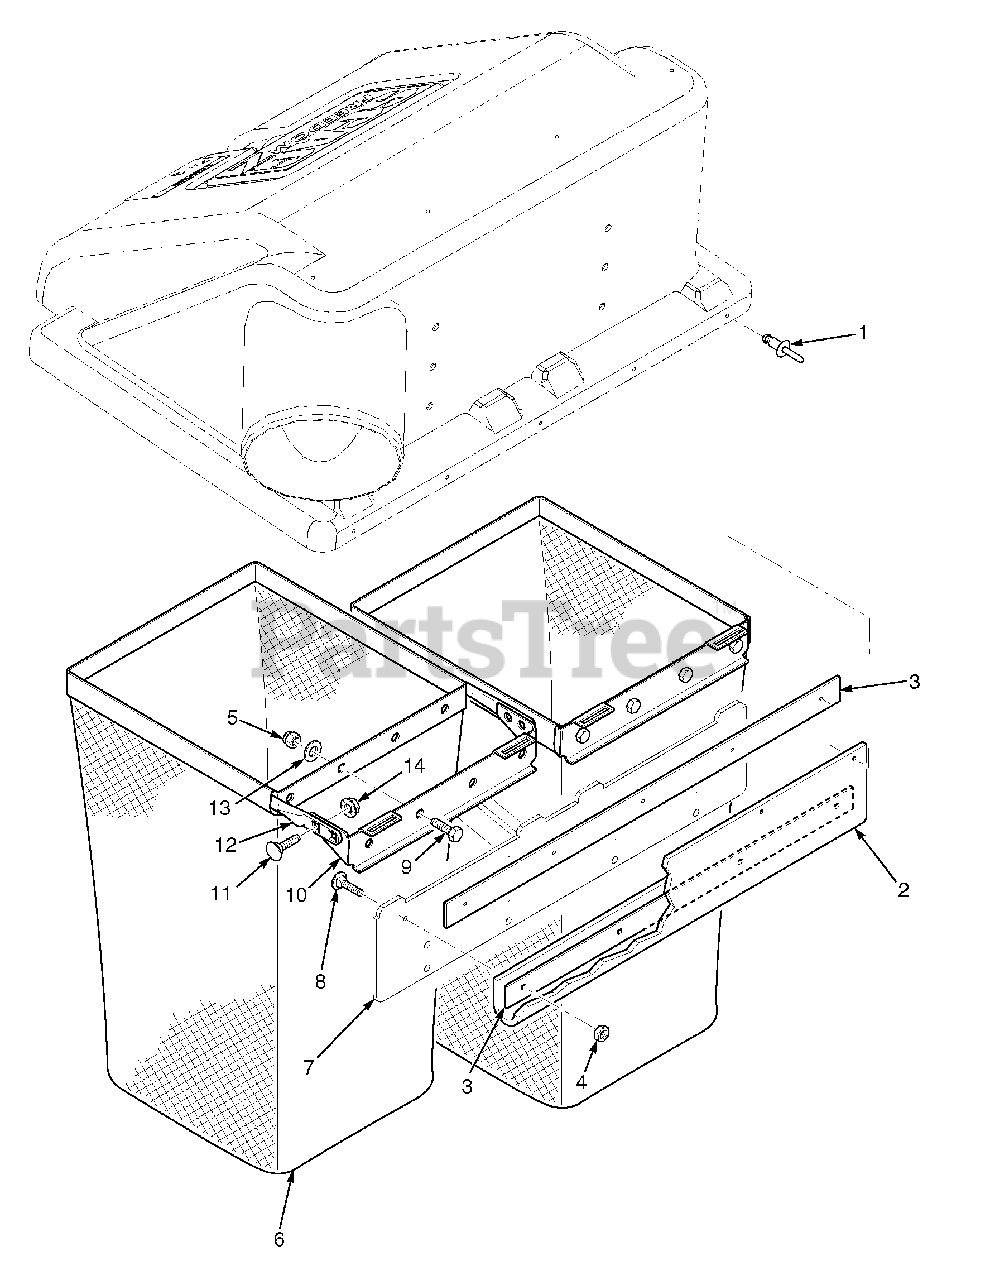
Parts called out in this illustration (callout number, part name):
1	Pop Rivet, 3/16 x .652
2	Seal, GC Hood
3	Retainer, Seal
4	Nut, Center Lock 1/4-20
5	Nut, Elastic Stop 5/16-18
6	Bag Assembly
7	Frame Weldment, Bag Support
8	Bolt, Hex Head 1/4-20 x 3/4"
9	Bolt, Hex Head 5/16-18 x 3/4"
10	Mount, Bag Frame Tube
11	Bolt, Carriage 5/16-18 x 3/4"
12	Tube, Bag Support
13	Flatwasher, 5/16-.375 x .875 x .083
14	Nut, Serrated Flange 5/16-18
